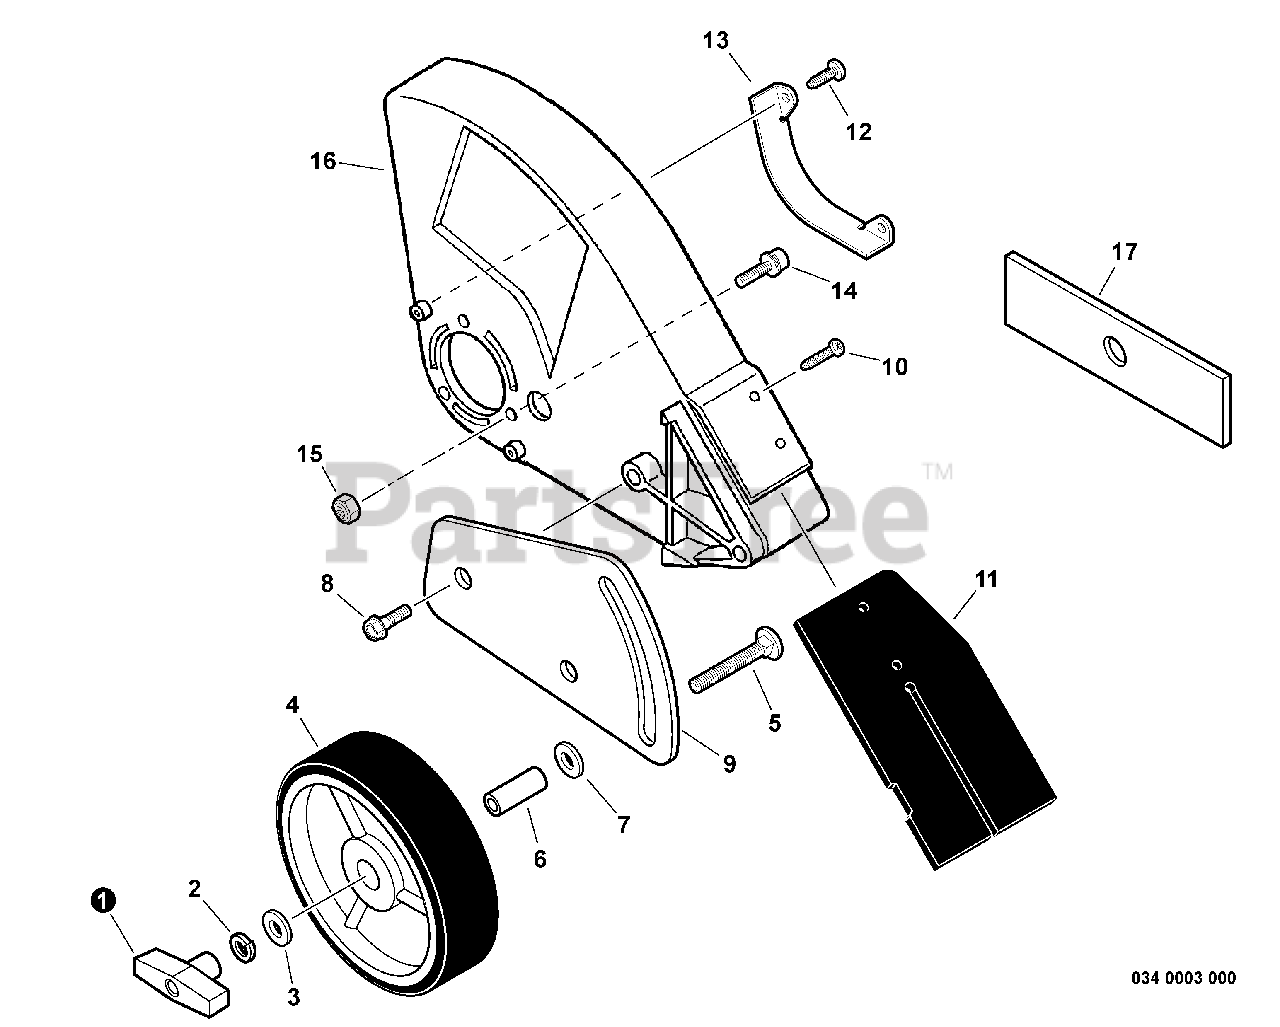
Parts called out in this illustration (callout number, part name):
1	KNOB, FASTENER
2	WASHER, SPRING 8
4	WHEEL
5	BOLT 5/16"-18×2-1/2"
6	COLLAR 12
7	WASHER, SPRING 10
9	BRACKET, WHEEL
11	FLAP, DEBRIS
13	GUARD, SHIELD
14	BOLT 5×22
15	NUT, LOCK M5
16	SHIELD, DEBRIS
17	BLADE - 2 PK
